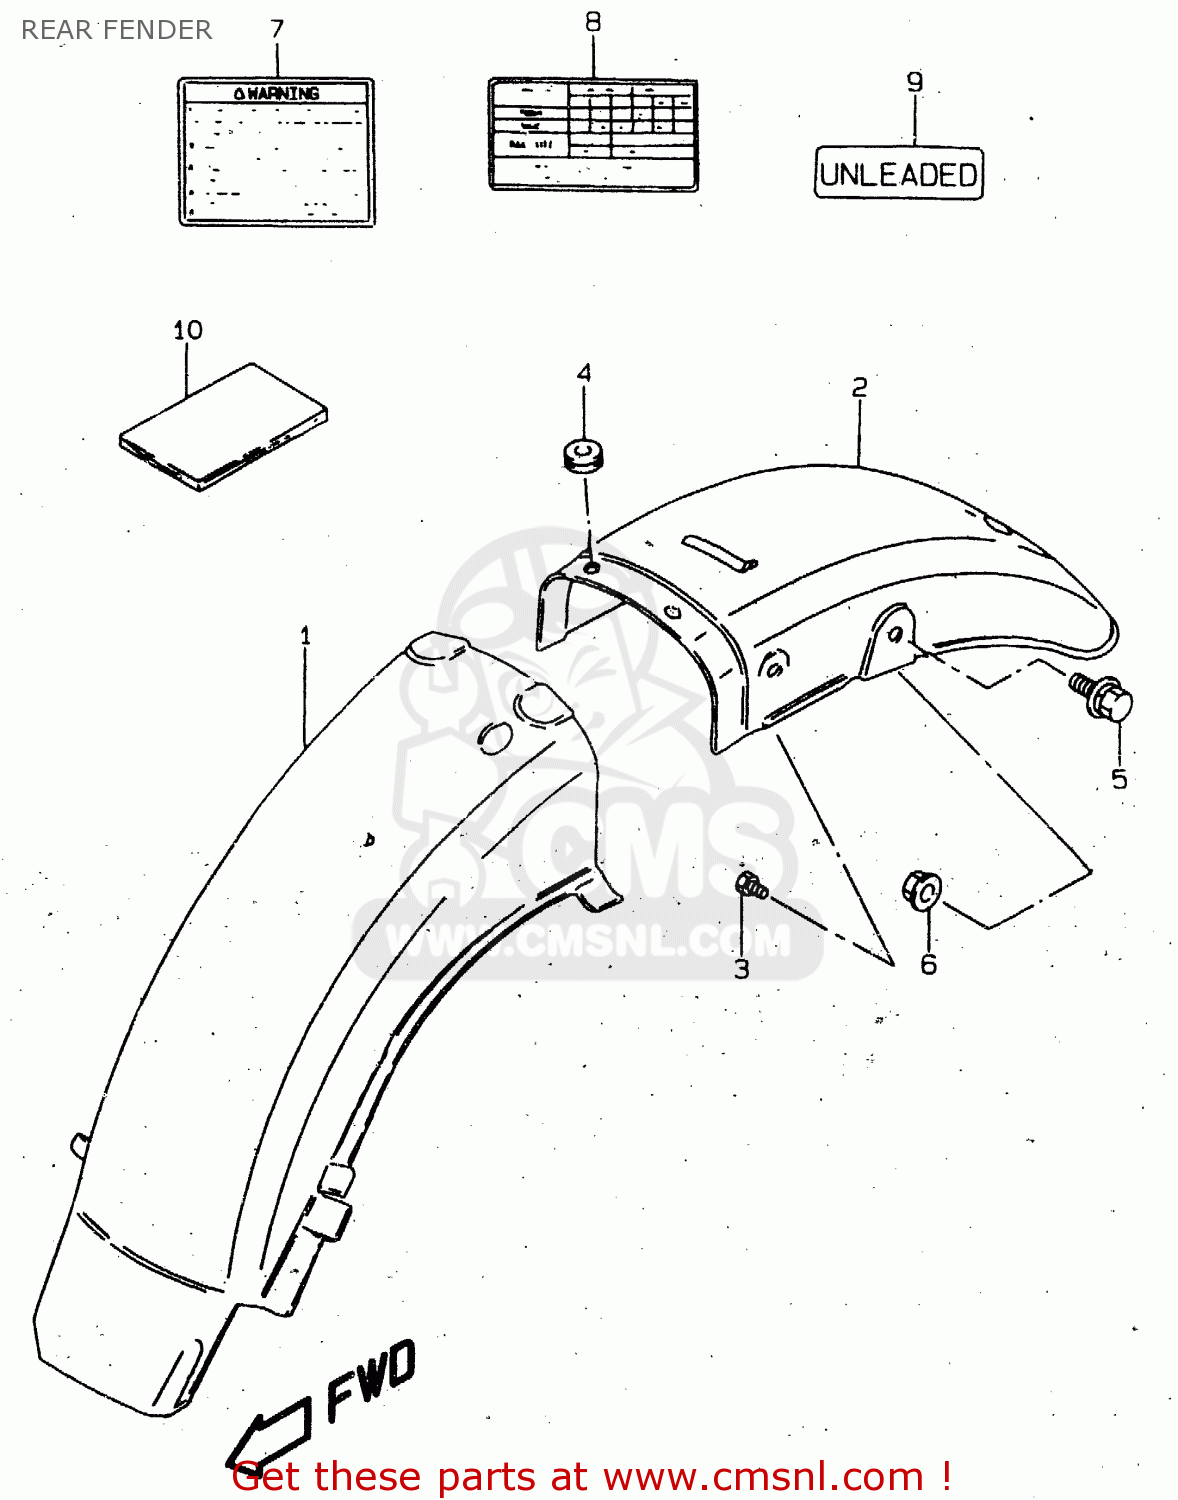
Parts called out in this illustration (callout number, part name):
1	BODY,FR
2	FENDER,RR
3	BOLT
4	CUSHION
5	BOLT
6	NUT
7	LABEL,WARNING
8	LABEL,TIRE INFORMATION
9	LABEL,CAUTION
10	MANUAL,OWNER'S
